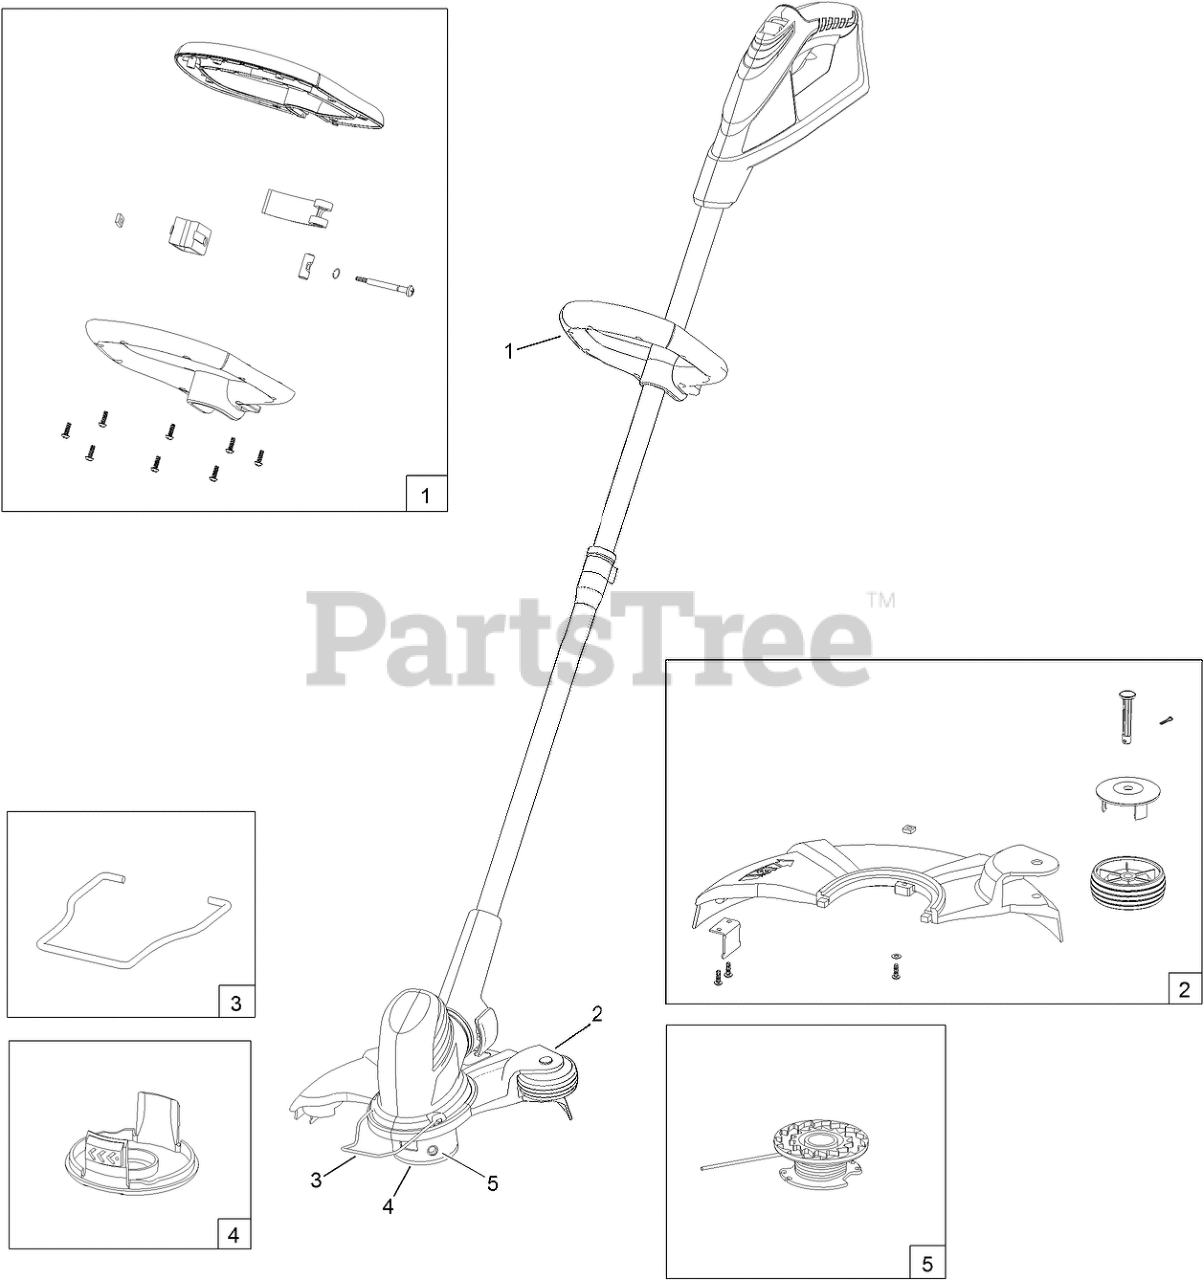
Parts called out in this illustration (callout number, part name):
1	ASSIST HANDLE ASM
2	SHIELD ASM
3	CLIP-GUIDE, EDGER
4	CAP-RETAINER, SPOOL
5	SPOOL-REPLACEMENT
